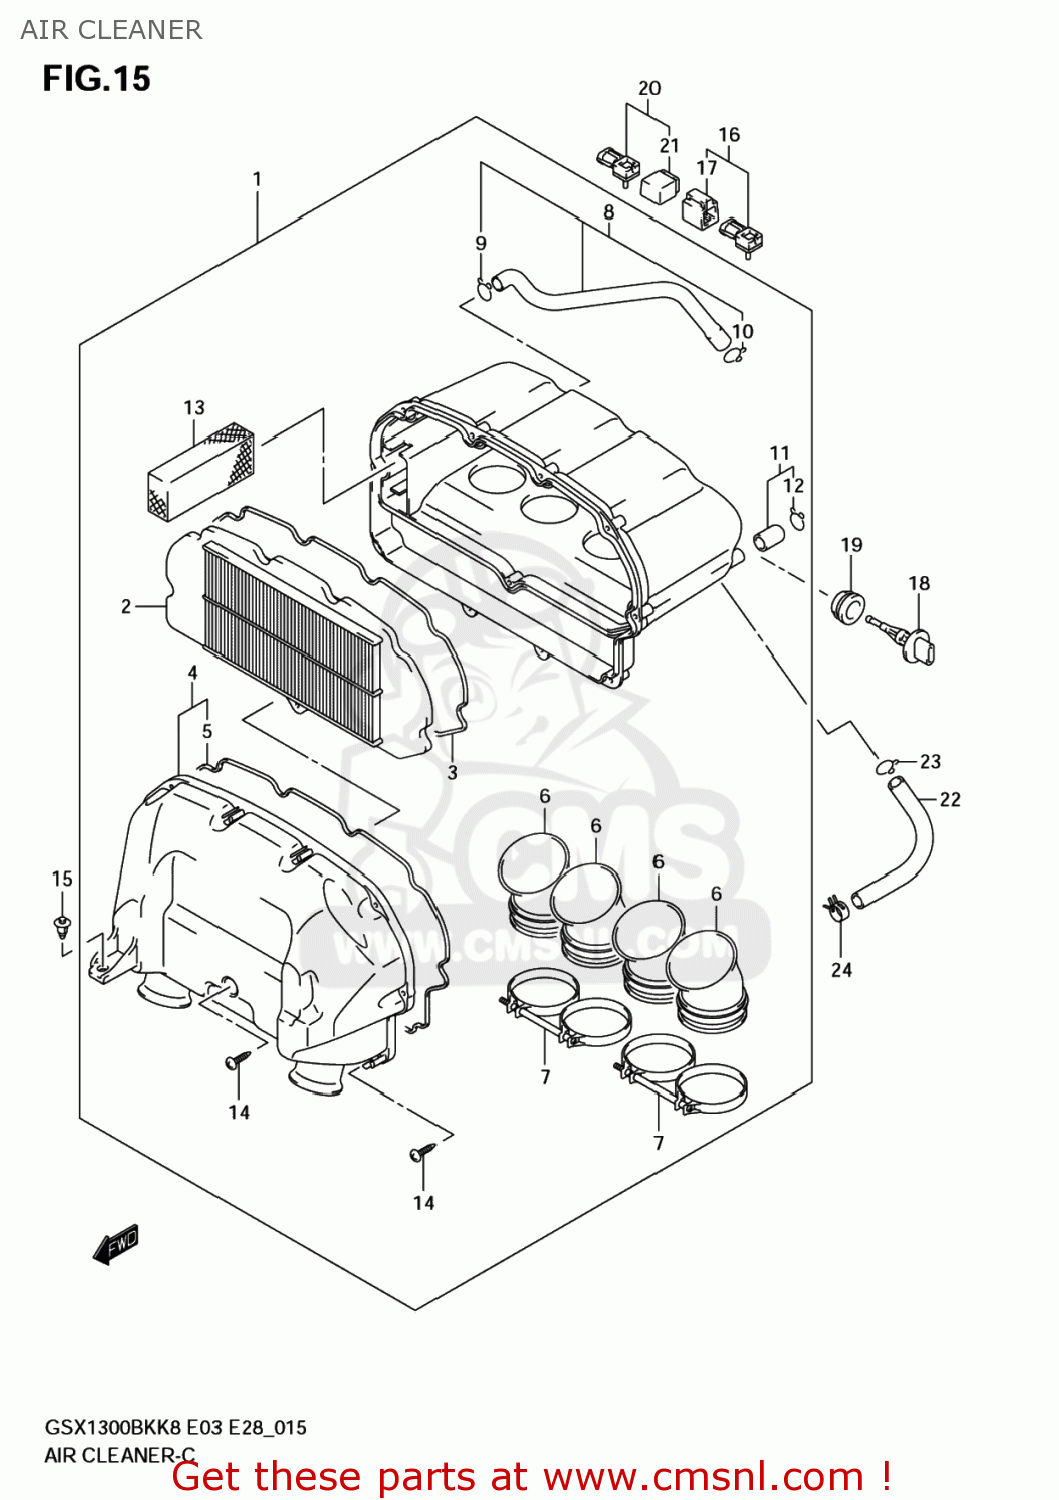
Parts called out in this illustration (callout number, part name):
1	CLEANER ASSY,AIR
2	FILTER ASSY
3	GASKET,CASE (NAS)
4	CAP,AIR CLEANER
5	GASKET,CAP (NAS)
6	TUBE,OUTLET B
7	CLAMP,INTAKE PIPE
8	TUBE,BREATHER
9	CLIP
10	CLIP
11	PLUG ASSY,DRAIN
12	CLIP
13	FILTER,BREATHER
14	SCREW
15	CLIP(BLACK)
16	SENSOR,BOOST
17	COVER
18	SENSOR,INLET AIR TEMP
19	GROMMET,AIR TEMP SENSOR
20	SENSOR,AIR PRESSURE
21	COVER
22	HOSE,ISC VALVE
23	CLIP
24	CLIP
